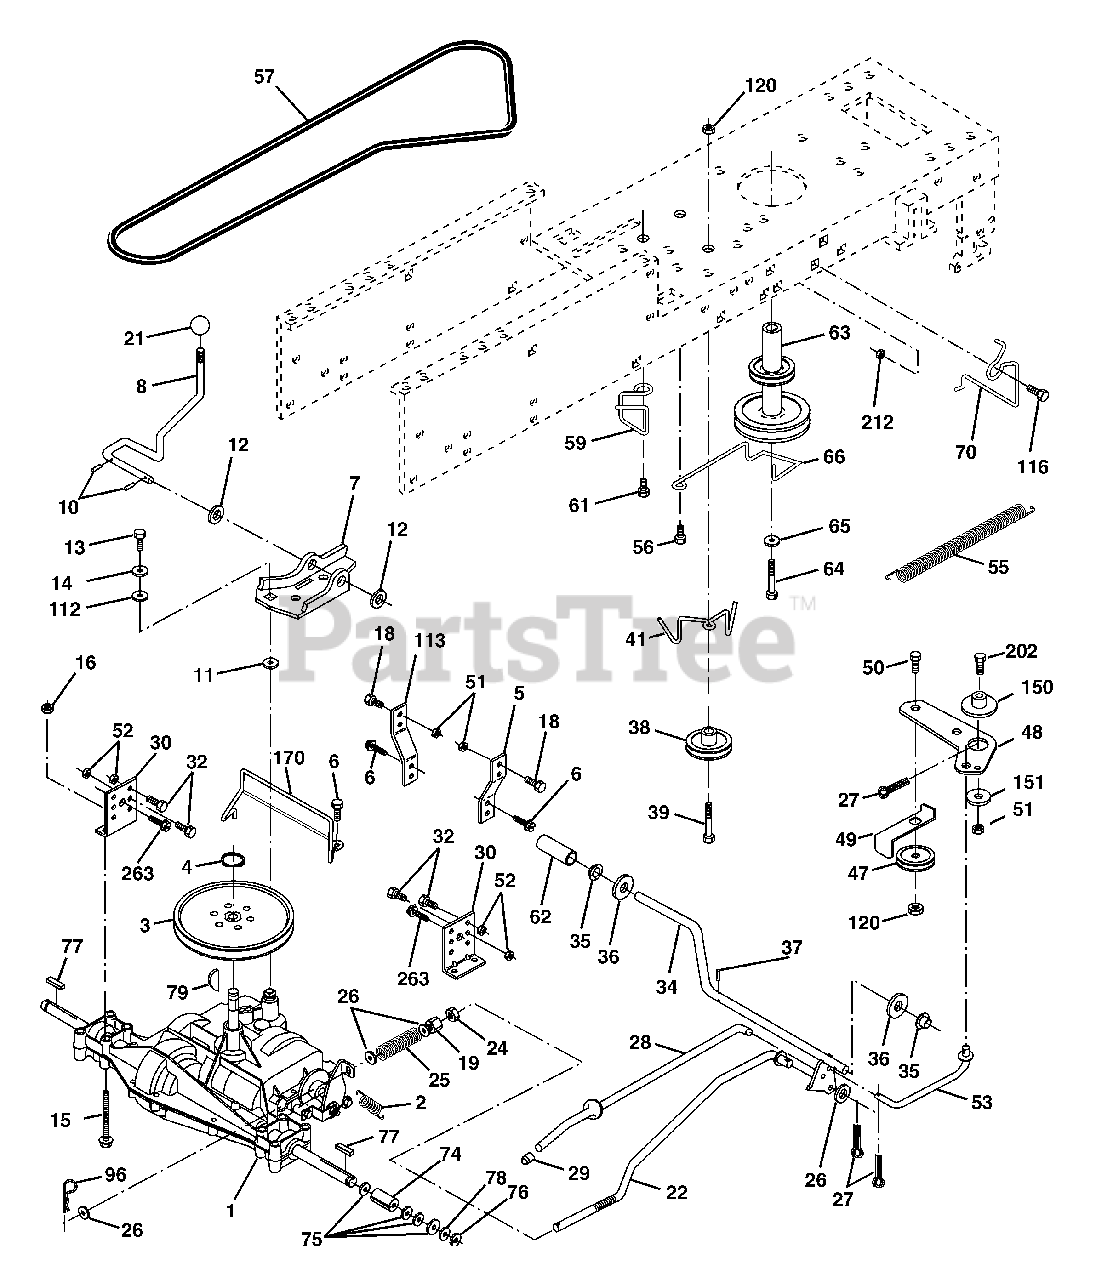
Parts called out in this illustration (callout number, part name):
2	Spring Return Brake
3	Pulley Transaxle 18"tires
4	Ring Retainer # 5100-62
5	Strap Torque 30 Degrees RH
6	Screw 5/16-18 x 3/4
7	Plate Rod Shift T/a
8	Rod Shifter Blk
10	Pin Cotter 1/8 x 1 Cad
11	Washer Plate Shf 388 Sq Hole
12	Washer 15/32 x 3/4 x 16 Ga.
13	Bolt 1/4-28 unf Gr. 8 w/Patch
14	Washer Lock Hvy Helical 1/4
15	Bolt Hex Flghd 5/16-18 Gr. 5
16	Nut 5/16-18
18	Bolt Fin Hex 3/8-16 unc x 1 Gr. 5
19	Nut lock Hex w/Ins 3/8-16 unc
21	Knob Rd 1/2-13 Plstc Thds Blk
22	Rod Brake LT
24	Nut Hex Jam 3/8-16 unc
25	Spring Rod Brake 2 00 Zinc
26	Washer 13/32 x 13/16 x 16 Ga.
27	Pin Cotter 1/8 x 3/4 Cad
28	Rod Brake Parking LT/YT
29	Cap Brake Parking Black
30	Bracket Transmission
32	Bolt Fin Hex 5/16-18 x 3/4
34	Shaft Asm Pedal Foot Nibbed
35	Bearing Nylon Blk 629 Id
36	Washer 21/32 x 1 x 16 Ga.
37	Pin Roll 3/16 x 1"
38	Pulley Composite Flat
39	Bolt 3/8-16 x 2-3/4
41	Keeper Belt Idler
47	Pulley Idler V Groove Plastic
48	Bellcrank Clutch Grnd Drv STL
49	Retainer Belt Style Spring
50	Bolt Carr Sh 3/8-16 x 1-1/2 Gr. 5
51	Nut Crownlock 3/8-16 unc
52	Nut Crownlock 5/16-18 unc
53	Link Clutch 7 66
55	Spring Return Clutch 6 75
56	Screw 3/8-16 x 1-1/4
57	V-Belt Ground Drive 95
59	Keeper Belt Chassis Span Ctr
61	Screw 3/8-16 x .875
62	Cover Pedal Blk Round
63	Engine Pulley LT/YT
64	Bolt Hex 7/16-20 x 4 Gr. 5
65	Washer Lock Hvy Hlcl Spr 7/16
66	Keeper Belt Engine
70	Guide Belt Mower Drive RH
74	Spacer Axle
75	Washer 25/32 x 1 1/4 x 16 Ga.
76	E-ring #5133-75
77	Key Square 2 0 x 1845/ 1865
78	Washer 25/32 x 1-5/8 x 16 Ga.
79	Key Woodruff
96	Retainer Spring 1"
112	Washer 9/32 x 3/4 x 10 Ga.
113	Strap Torque 90 Degrees LH
116	Bolt Rdhd Sq Neck 3/8-16 x 1
120	Nut Lock Flg 3/8-16
150	Spacer Retainer Lt
151	Washer 13/32 x 2 x 10 Ga.
170	Keeper, Belt Transaxle
202	Bolt Carr Sh 3/8-16 x 1-3/4 Gr. 5
212	Nut Hex Flg Lock
263	Screw 3/8-16 x 3/4
